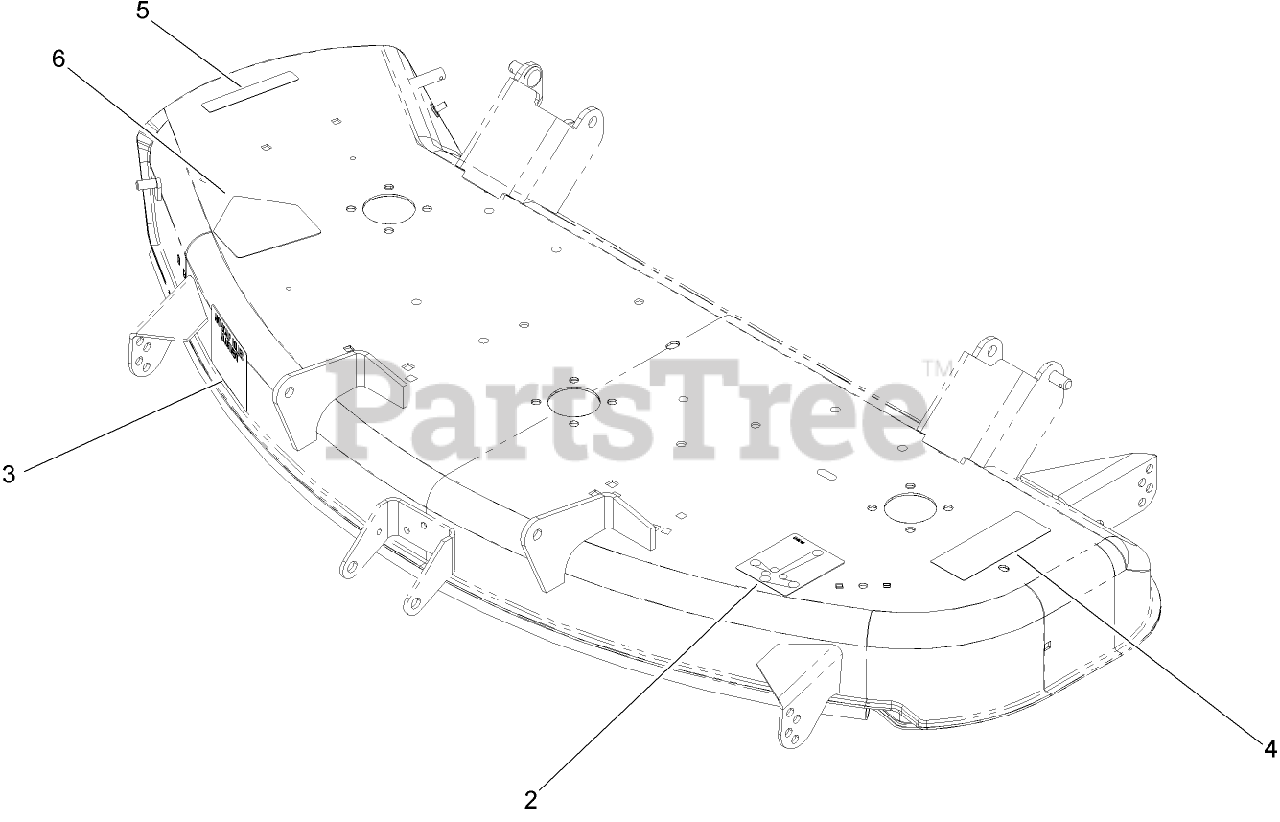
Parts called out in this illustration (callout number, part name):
2	DECAL-ROUTING, BELT
3	DECAL-WHEEL, GAGE
4	DECAL-DANGER
5	DECAL-CAUTION
6	DECAL-DANGER
